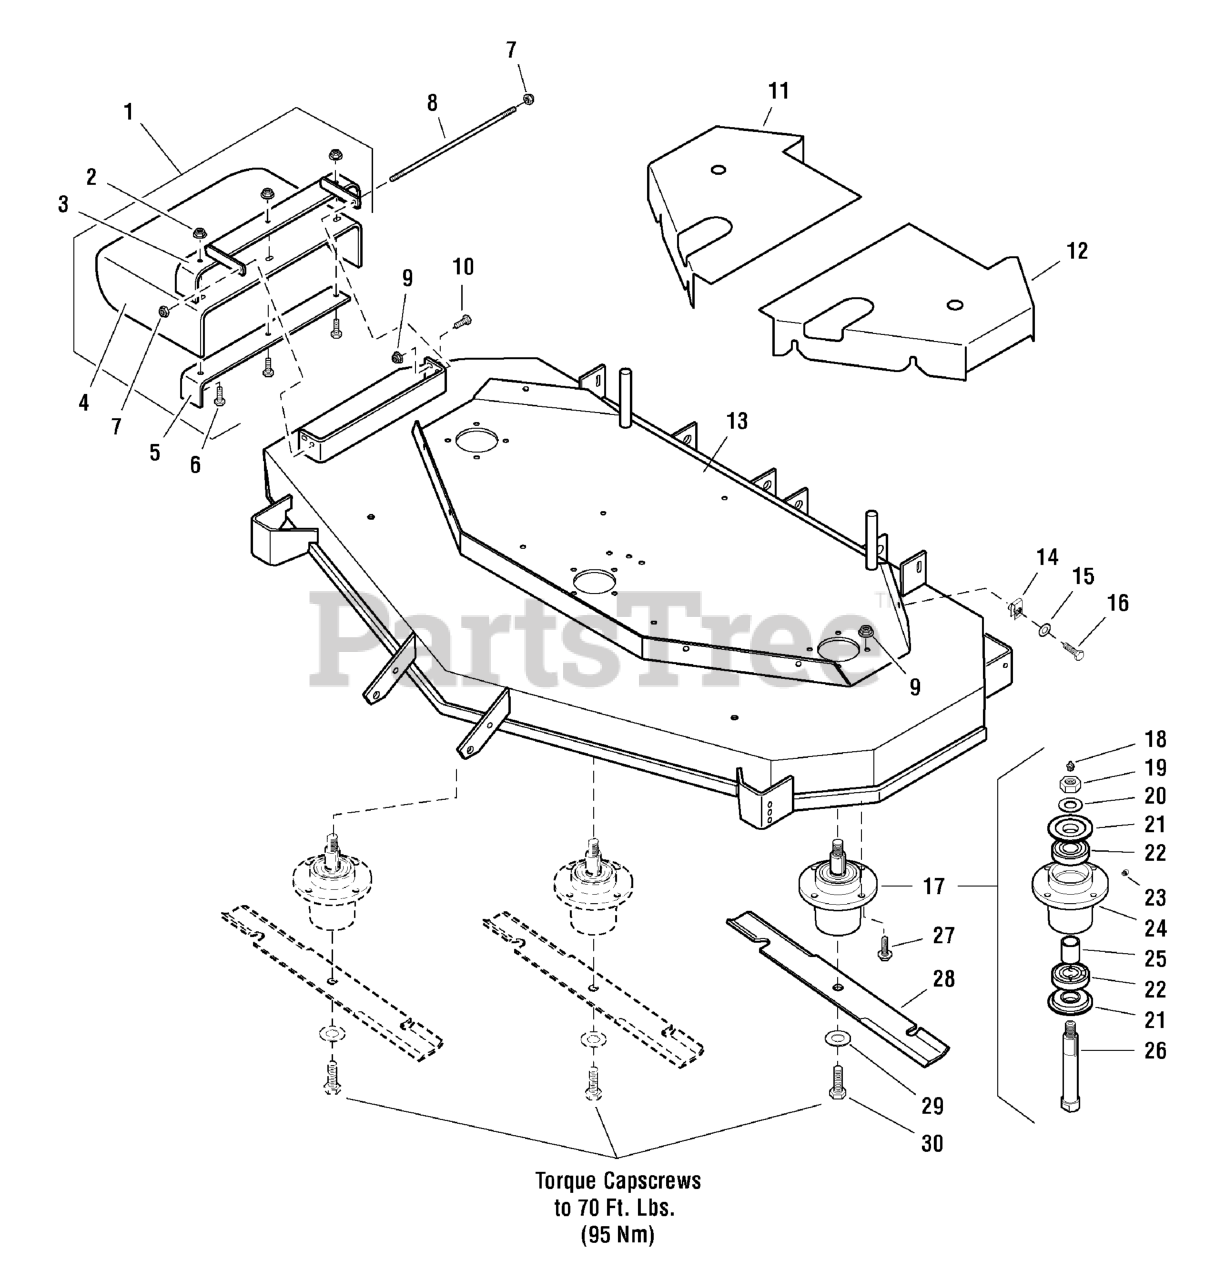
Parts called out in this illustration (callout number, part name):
1	61" RUBBER CHUTE ASSEMBLY, Complete
2	NUT, 3/8-16 Hex Nylock Flange
3	CHUTE FRAME
4	RUBBER CHUTE
5	CHUTE SUPPORT
6	BOLT, 3/8-16 X 1-1/4" GD5 CZ
7	NUT, 5/16-24 HEX NYLON LOCK
8	CHUTE MOUNT ROD
9	NUT, 5/16-18 Hex Nylock Flange
10	BOLT, 5/16-18 X 3/4 GD5
11	SPINDLE COVER - RH
12	SPINDLE COVER - LH
13	DECK SHELL W/DECALS, 61"
14	BODY CLIP, 5/16-18-7GA MATERIAL
15	WASHER, 5/16" SAE
16	BOLT, 5/16-18 X 3/4 GD5
17	ASSM, SPINDLE, LOW PROFILE
18	GREASE FITTING
19	NUT, 3/4-16 Hex
20	WASHER, 3/4 BELLEVILLE
21	TRASH SHIELD
22	BEARING
23	RELIEF VALVE
24	SPINDLE HOUSING
25	SPACER, 1.00 x 1.25 x 1.75
26	SPINDLE SHAFT
27	BOLT, Flange Head, 5/16-18 x 1-1/4
28	MOWER BLADE, 21"
29	WASHER, 5/8" USS
30	BOLT, 5/8-11 X 1-3/4 GD8
